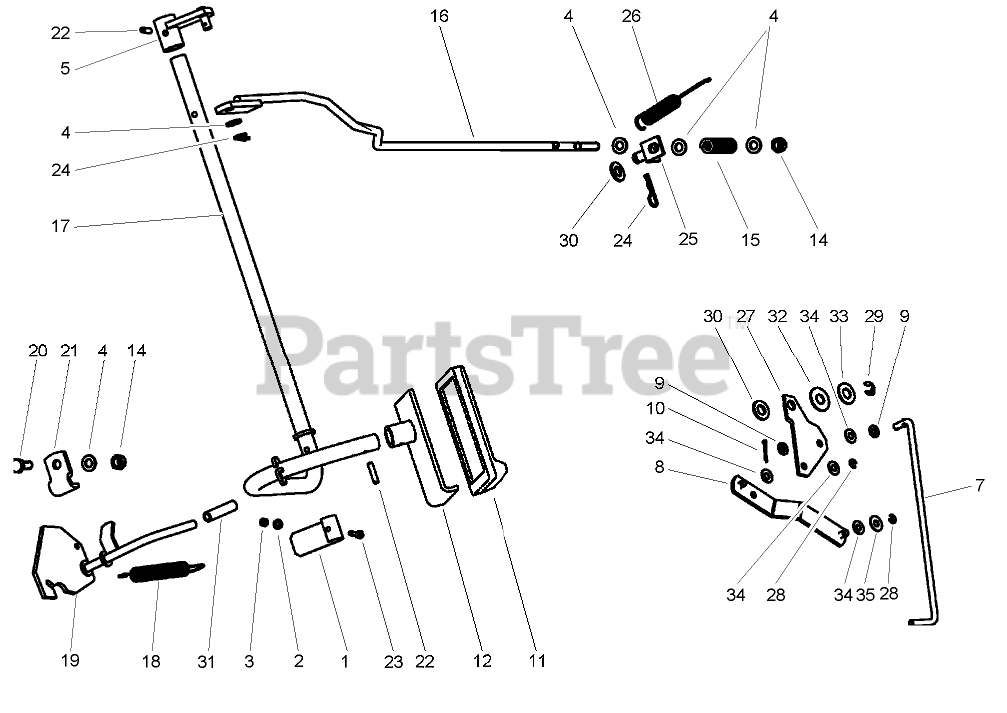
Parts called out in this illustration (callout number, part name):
1	LEVER-SPRING
2	WASHER
3	NUT-HEX
4	WASHER-PLAIN
5	BRACKET-ROD, BRAKE
7	ROD-LEVER, BYPASS
8	Lever-Bypass
9	WASHER
10	PIN-COTTER
11	PAD-PEDAL
14	NUT-LOCK, NI
15	SPRING-BRAKE
16	ROD-CONNECTING, BRAKE
17	Shaft-Brake
18	SPRING-BRAKE, HAND
19	LEVER-BRAKE, HAND
20	SCREW-HH
21	CLAMP-LEVER, PARKING BRAKE
22	PIN-SPRING
23	SCREW-HEX
24	PIN-COTTER
25	BRACKET-ROD, BRAKE
26	SPRING
27	Plate-Bypass
28	STIRRUP
29	E-CLIP
30	WASHER-FLAT
32	Washer
33	Washer
34	Washer
35	Washer
